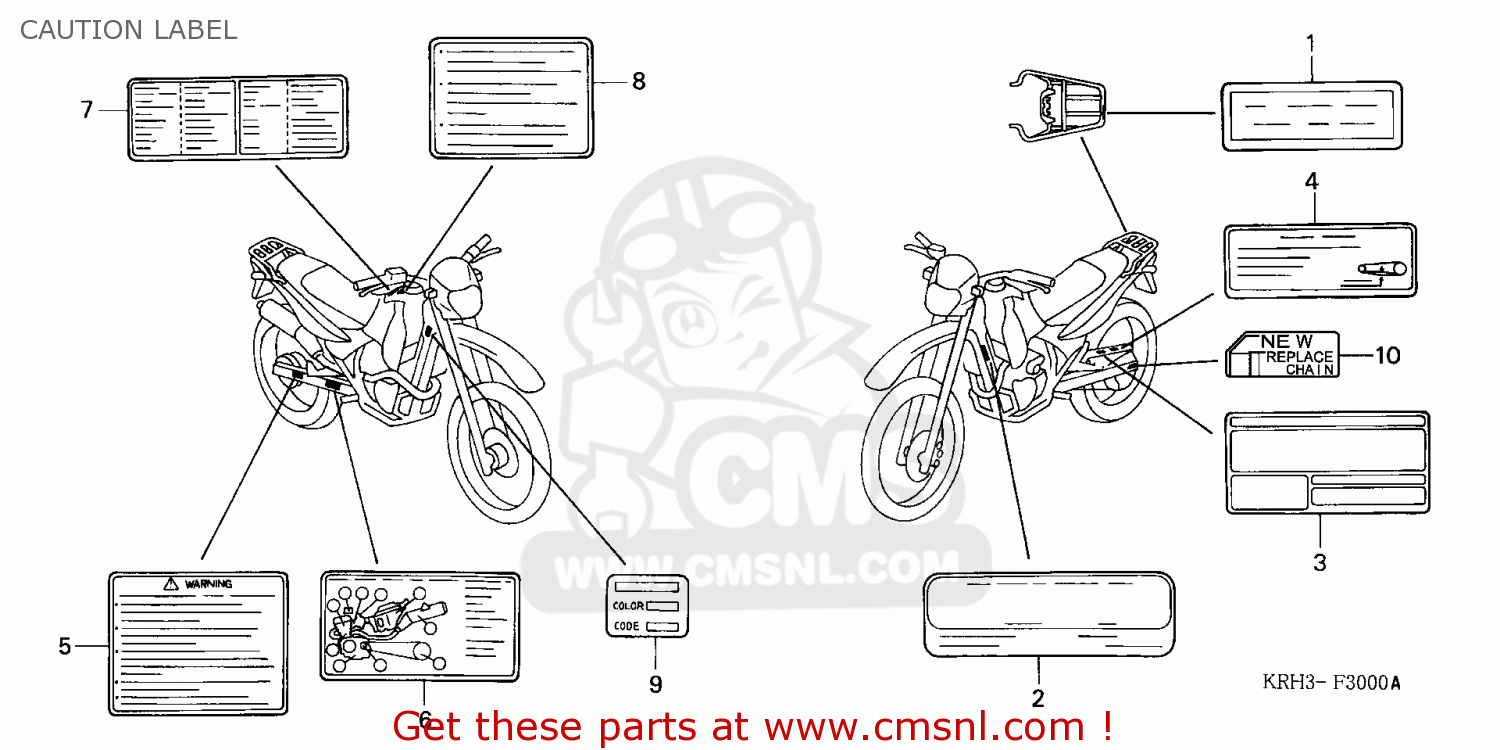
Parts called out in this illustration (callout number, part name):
1	LABEL,REAR*TYPE2*
2	PLATE,REGISTERED
3	LABEL,TIRE
4	LABEL,DRIVE CHAIN
5	LABEL,ACCESSORY L
6	LABEL,TAMPER PROO
8	LABEL,DRIVE
9	LABEL,COLO*TYPE1*
10	LABEL CHAIN ADJ
